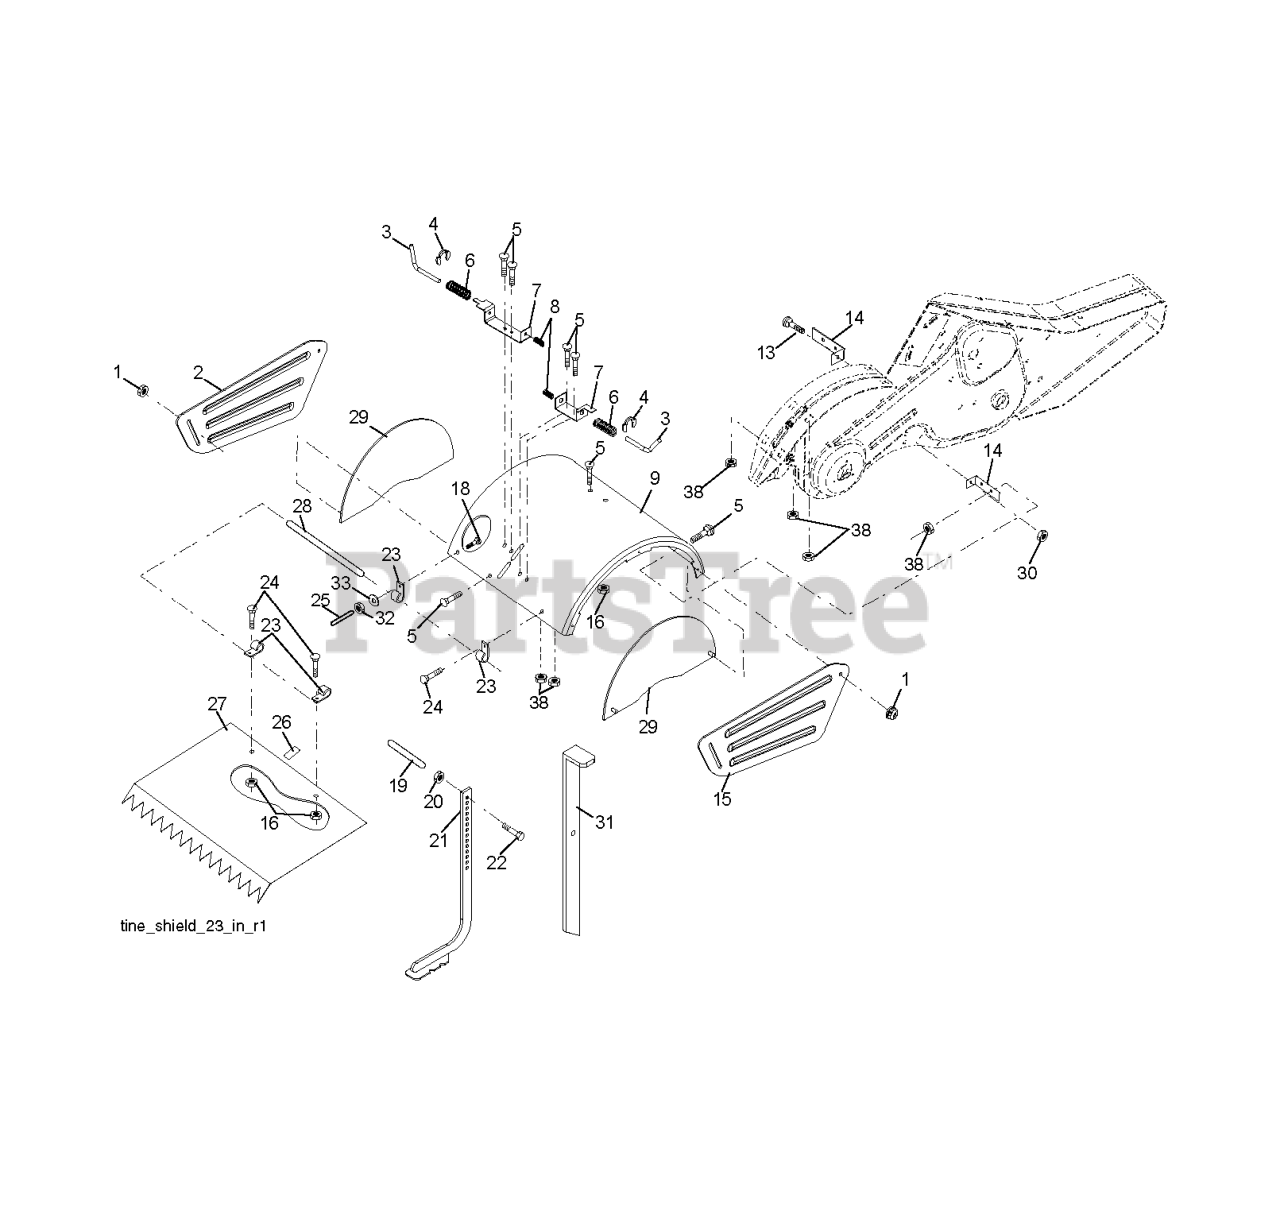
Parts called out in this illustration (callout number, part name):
1	NUT LOCK HEX FLANGE 5/16-18
2	SHIELD
3	STAKE PIN TI
4	RING, KLIP
5	BOLT, RDHD SQNK 5/16-18 X 3/4
7	BRACKET.LATCH.STAKE.3.20.BLACK
8	SPRING CRT
9	SHIELD.PNT.TINE.17"M
13	BOLT.CARRIAGE.5/16-18
14	BRACKET.TINE.SHIELD.TILLER
15	SIDE SHIELD RH
16	NUT T
20	NUT.HEX.3/8-16UNC
21	STAKE.DEPTH.16.CRT.BLACK
22	BOLT.375-16
25	VINYL CAP TI
26	PAD IDLER TI
27	SHIELD LEVELING
28	PIN.HINGE.TILLER
29	SHIELD.ASM.SIDE.ORANGE.(OLD)
30	LOCKNUT-FLANGE 5/16-18
31	RP.STAKE.DEPTH.DRAG.TILLR.GREY
32	NUT
33	LOCKWASHER
38	NUT
